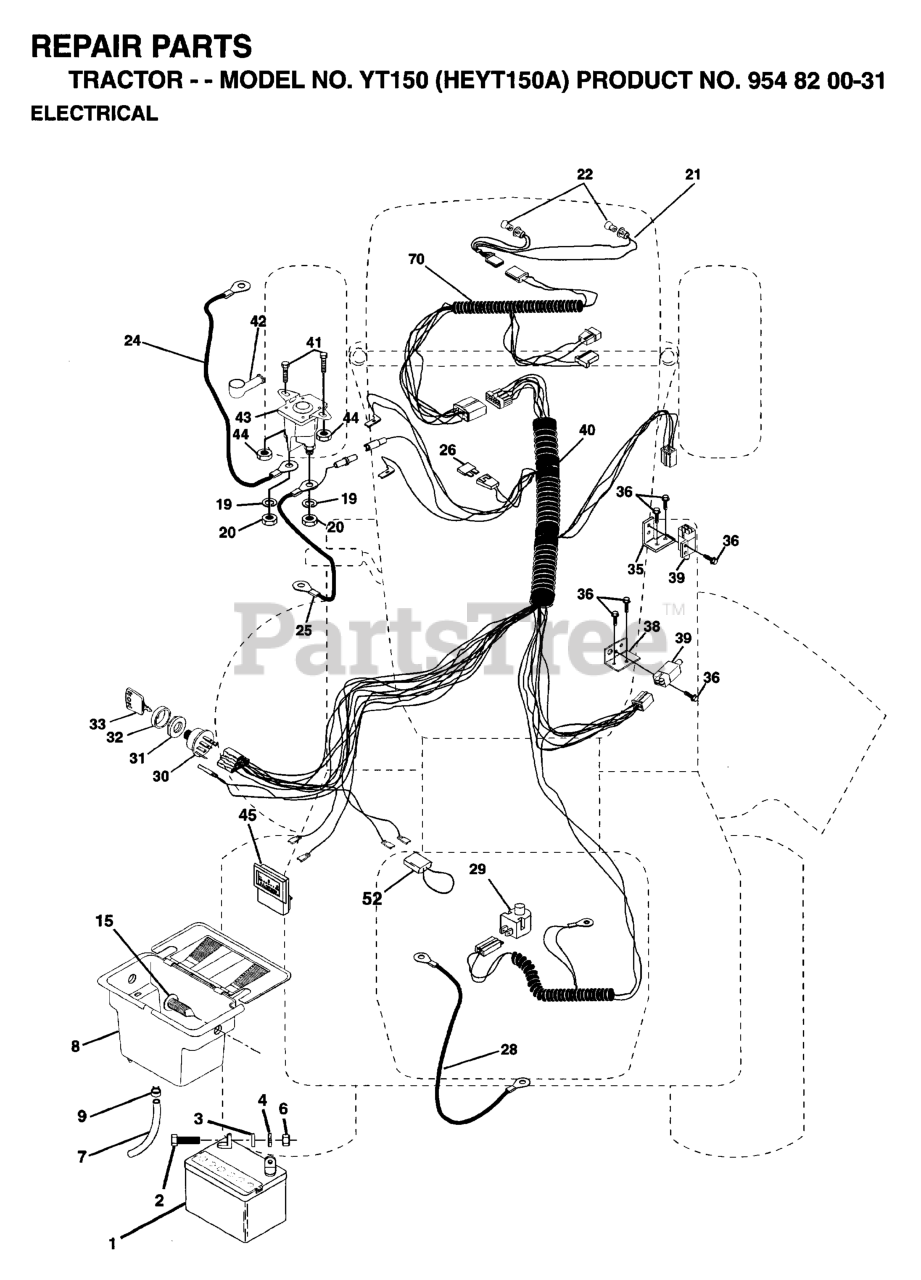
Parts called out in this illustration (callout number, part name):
1	BATTERY
2	BOLT.HEX.1/4.X.3/4.DICHROMATE
4	LOCKWASHER
6	NUT
7	TUBE BATTERY DRAIN
8	BATTERY CASE
9	HOSE CLAMP T
15	FASTERER SNAP-IN
19	LOCKWASHER
20	NUT
21	HARNESS LIGHT SOCKET
24	BATTERY CABLE GT
25	CABLE BATTERY
28	CABLE T
29	RP.SWITCH.PLUNGER.NC.GRAY
30	SWITCH.IGNITION.4.POSITION
31	NUT IGNITION
32	COVER SWITCH KEY
33	KEY.MOLDED.GENERIC
35	BRACKET LT
38	SWITCH BRACKET
39	SWITCH INTERLOCKT
40	HARNESS IGNITION
41	BOLT
42	TERMINAL COVER
43	SOLINOID
44	Nut, Keps Blk Hex 1/4-20 UNC
45	AMMETER
52	WIRE PROTECTION LOOP
70	HARNESS ENGINE
